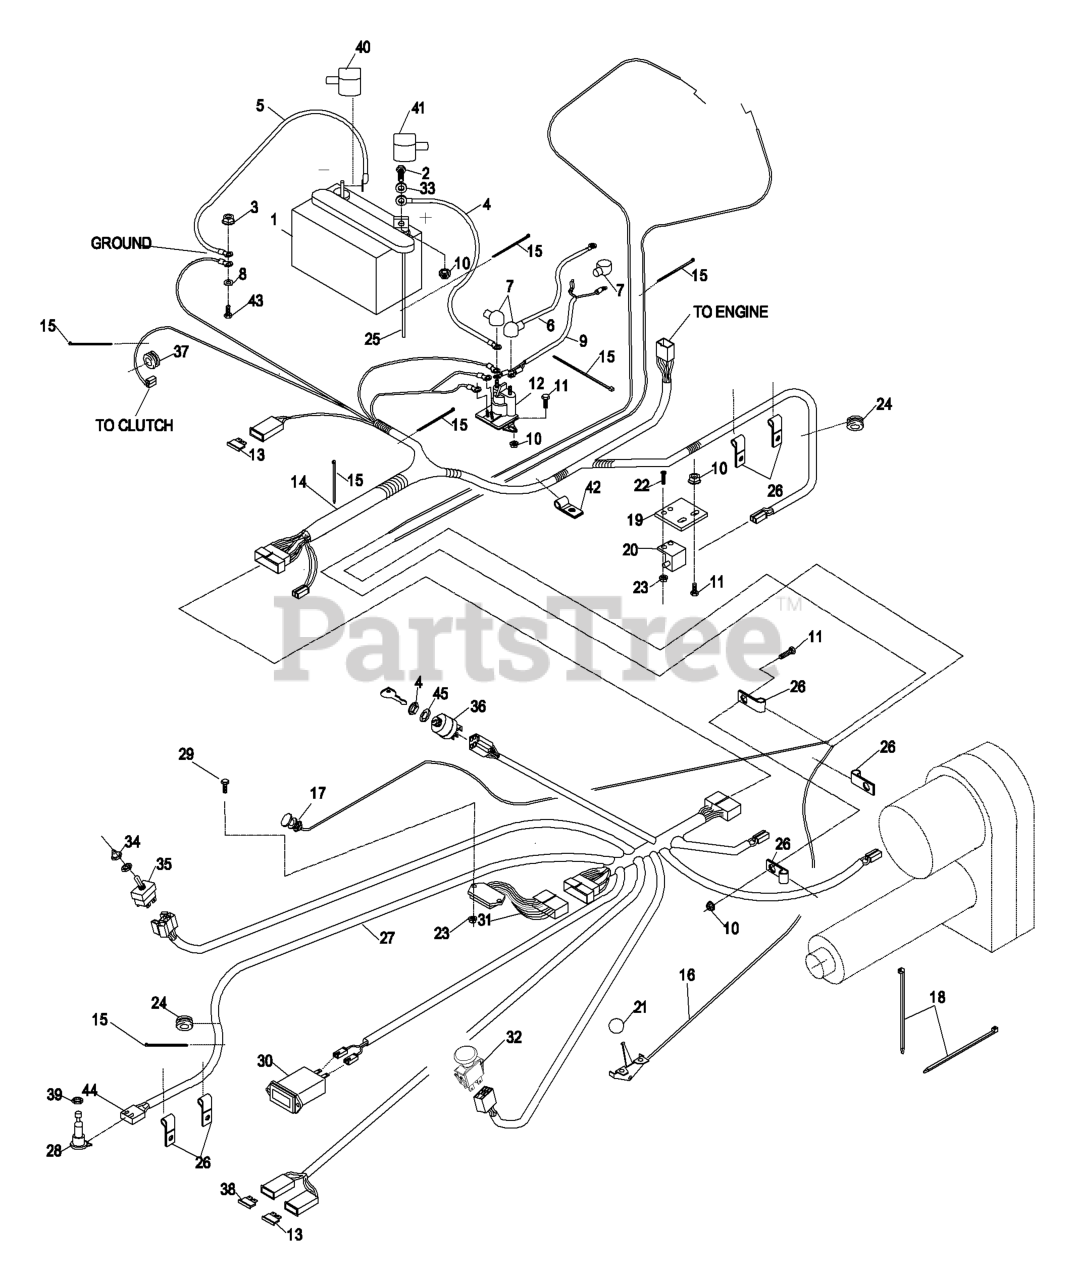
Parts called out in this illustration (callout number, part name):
2	SCREW-HH
4	SEAL-SWITCH, IGNITION
5	WIRE-GROUND
7	INSULATOR-SOLENOID
8	WASHER-SPRING
11	SCREW-HH
13	FUSE-BLADE TYPE, 20 AMP
15	TIE-CABLE
16	THROTTLE CABLE ASM
17	CONTROL-CHOKE
18	TIE-PLASTIC
19	BRACKET,SAFETY SWITCH
20	SWITCH-OPEN, NORMALLY
21	KNOB-BALL
22	10-24 X 5/8 FLT HD MS
23	NUT-LOCK, NI
24	GROMMET
26	CLIP-LOOM
27	HARNESS,CONSOLE WIRING
28	SWITCH,PUSH BUTTON
30	METER-HOUR
31	MODULE,OPC
33	WASHER-FLAT
34	BOOT-SWITCH, TOGGLE
35	SWITCH-TOGGLE, DPDT
36	SWITCH,IGNITION
37	GROMMET
38	FUSE-BLADE TYPE, 30 AMP
41	INSULATOR, BATTERY -
42	CLIP-LOOM
43	SCREW-HH
44	CONNECTOR,PACKARD 2 WAY
45	NUT-SWITCH, IGNITION
